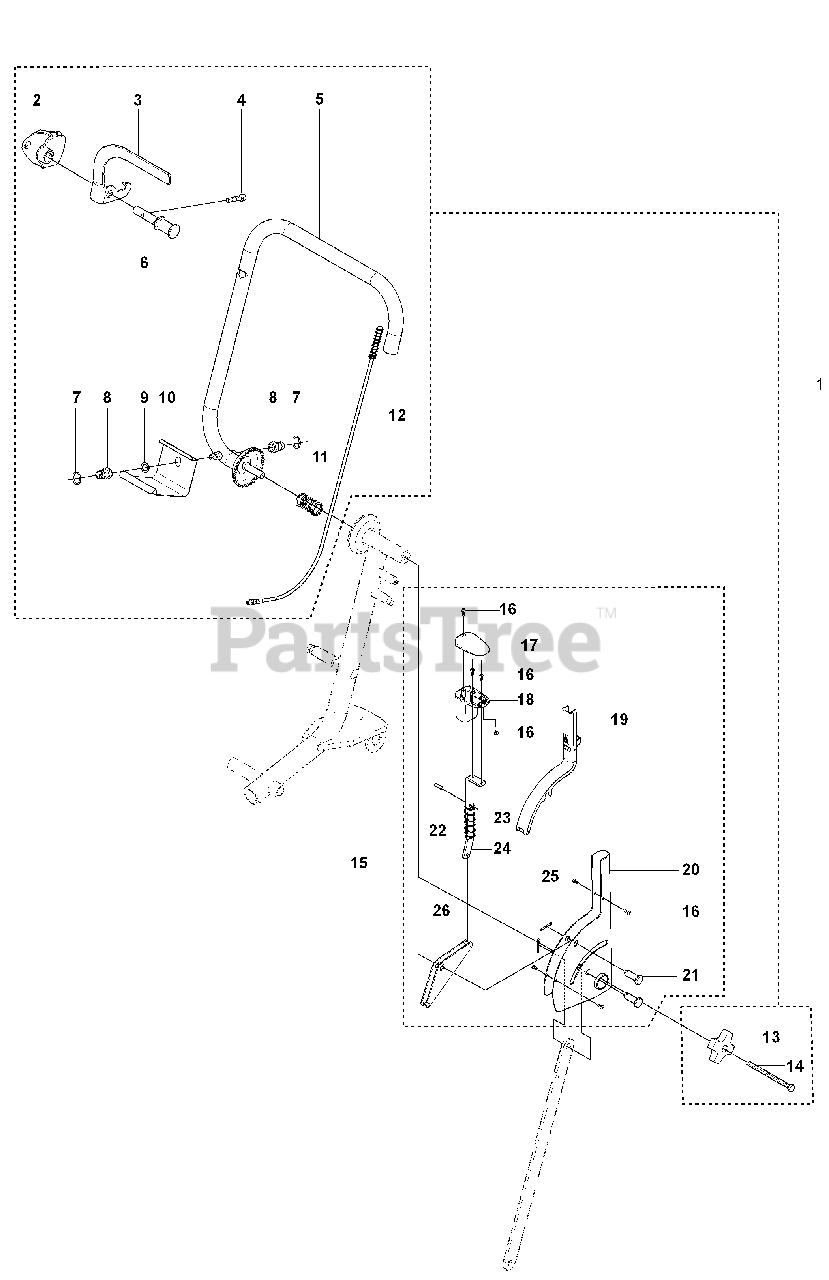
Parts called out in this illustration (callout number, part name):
1	HANDLEBAR ASSY
3	THROTTLE HANDLE ASSY
11	SPRING THROTTLE CONTROL
13	KNOB
15	LEVER
16	SCREW CROSS-SLOTTED
21	CLEVIS PIN
22	PIN SPRING
25	LOCKING PIN
